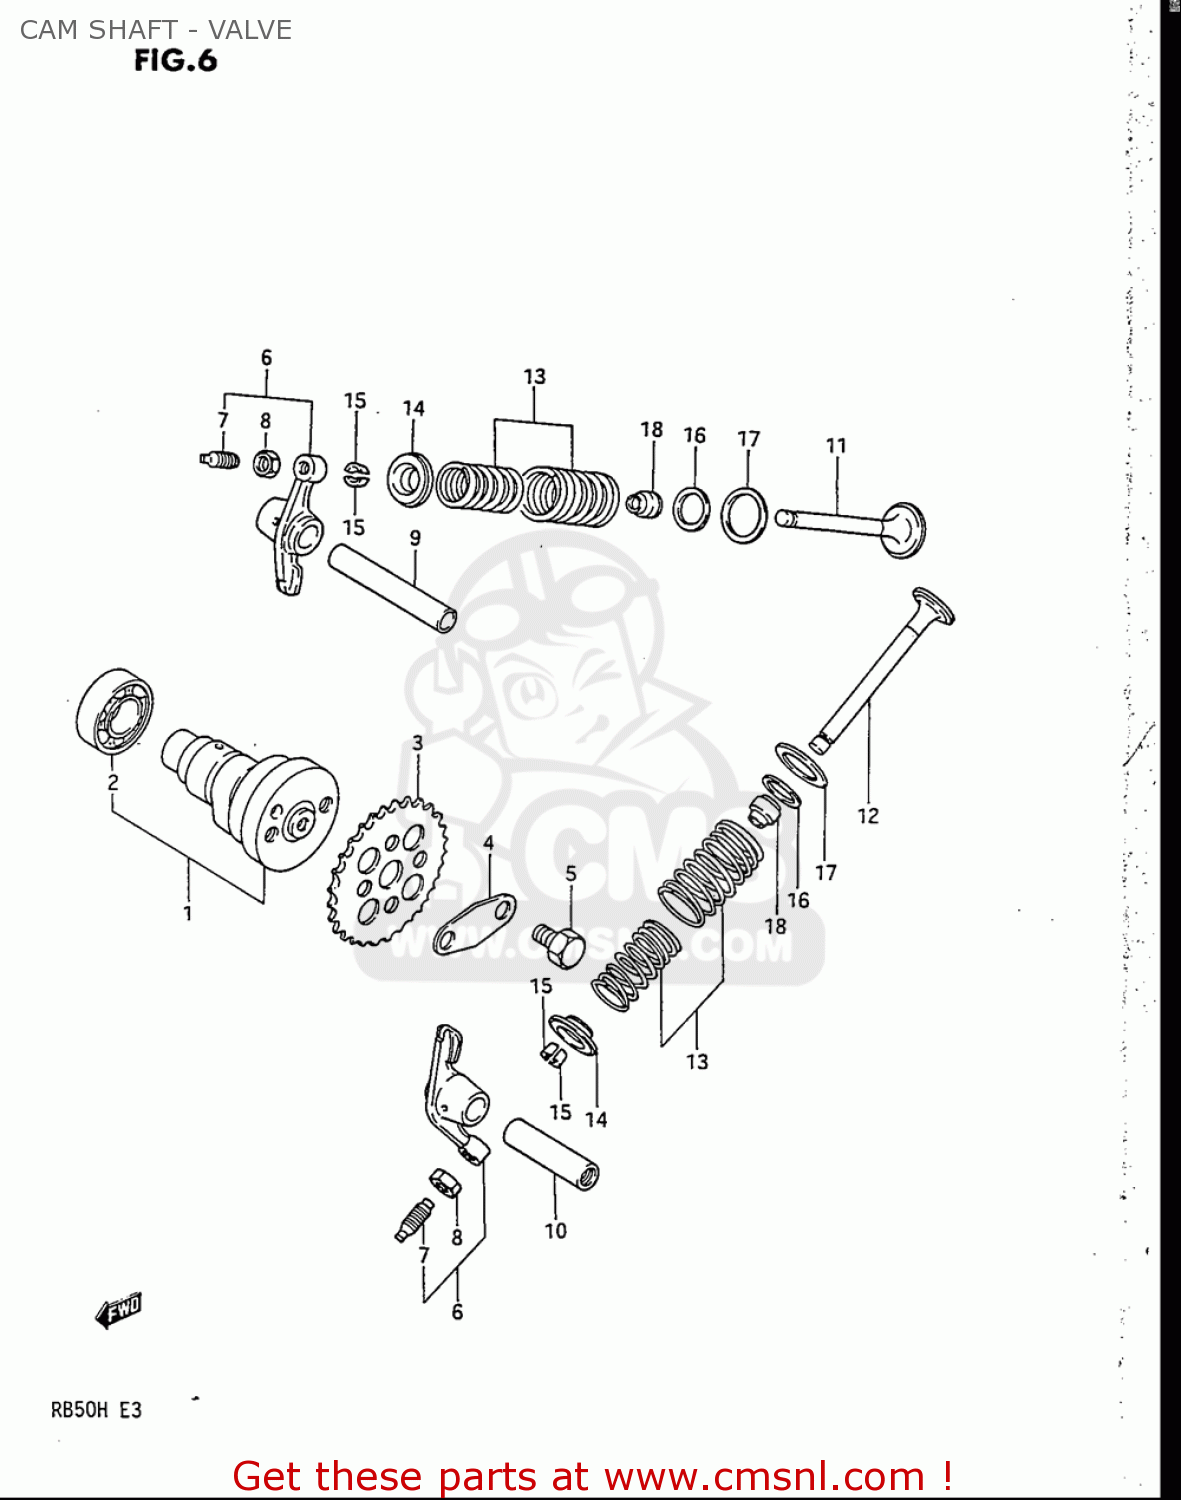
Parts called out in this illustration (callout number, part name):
2	BEARING(15X32X9)
3	SPROCKET,CAMSHAFT
4	WASHER,SPROCKET
5	BOLT(6X10.5)
6	ARM,VALVE ROCKER
7	SCREW,TAPPET ADJUSTING
8	NUT,TAPPET ADJUSTING
11	VALVE,INTAKE
12	VALVE,EXHAUST
15	COTTER VALVE
18	SEAL,OIL(5X10.5X8.4)
